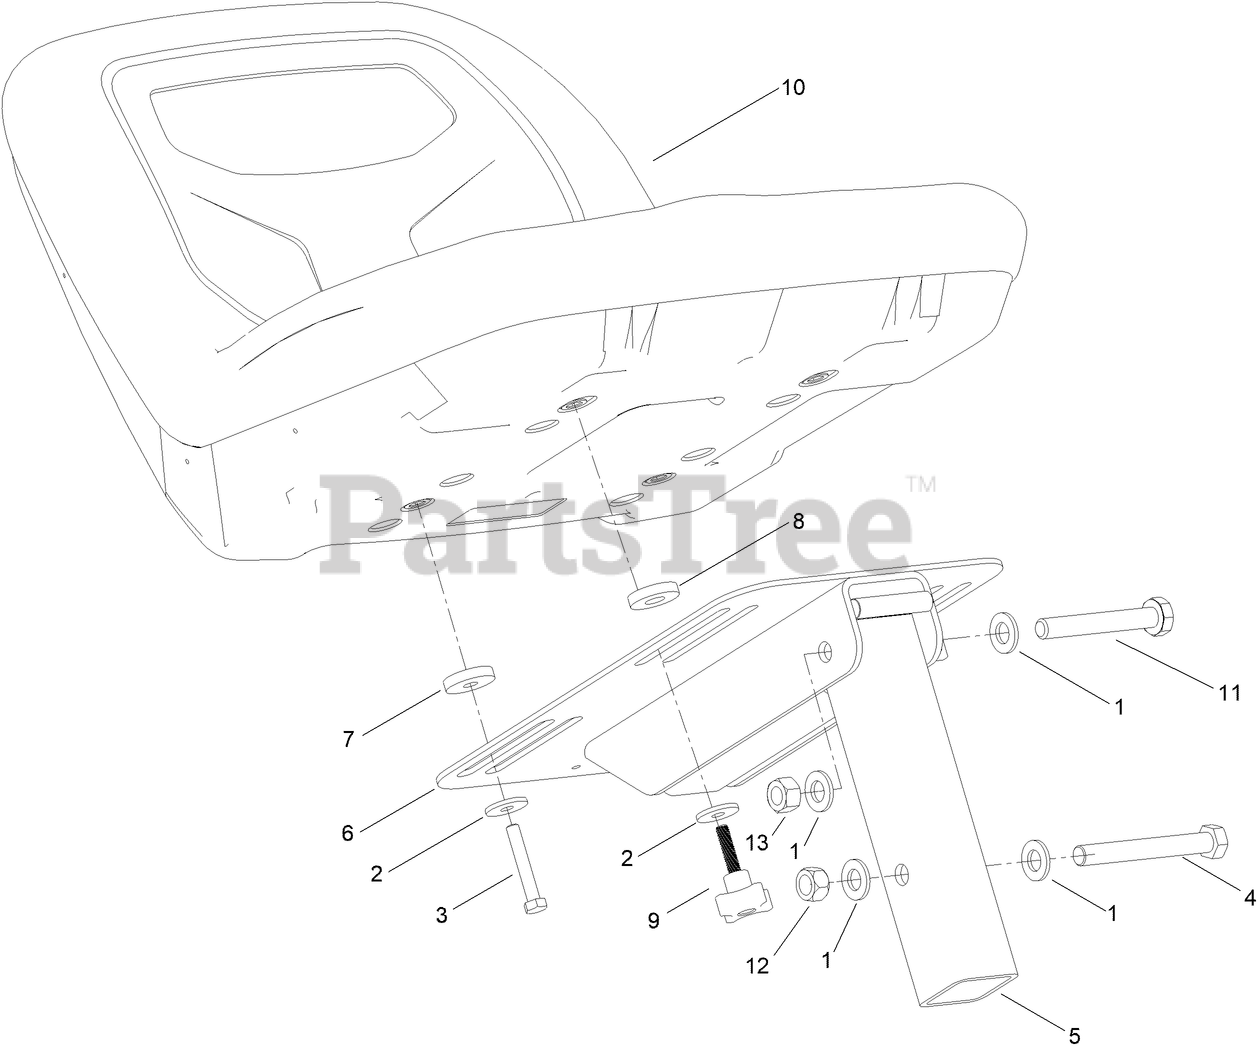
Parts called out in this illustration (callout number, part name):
1	WASHER-FLAT
2	WASHER-FLAT
3	SCREW-HH
4	SCREW-HH
5	BRACKET-SEAT
6	MOUNT-SEAT ASM
7	SPACER-SEAT ASM
8	SPACER-SEAT ASM
9	ADJUSTMENT SCREW-SEAT ASM
11	SCREW-HH
12	NUT-HEX
13	NUT-LOCK
